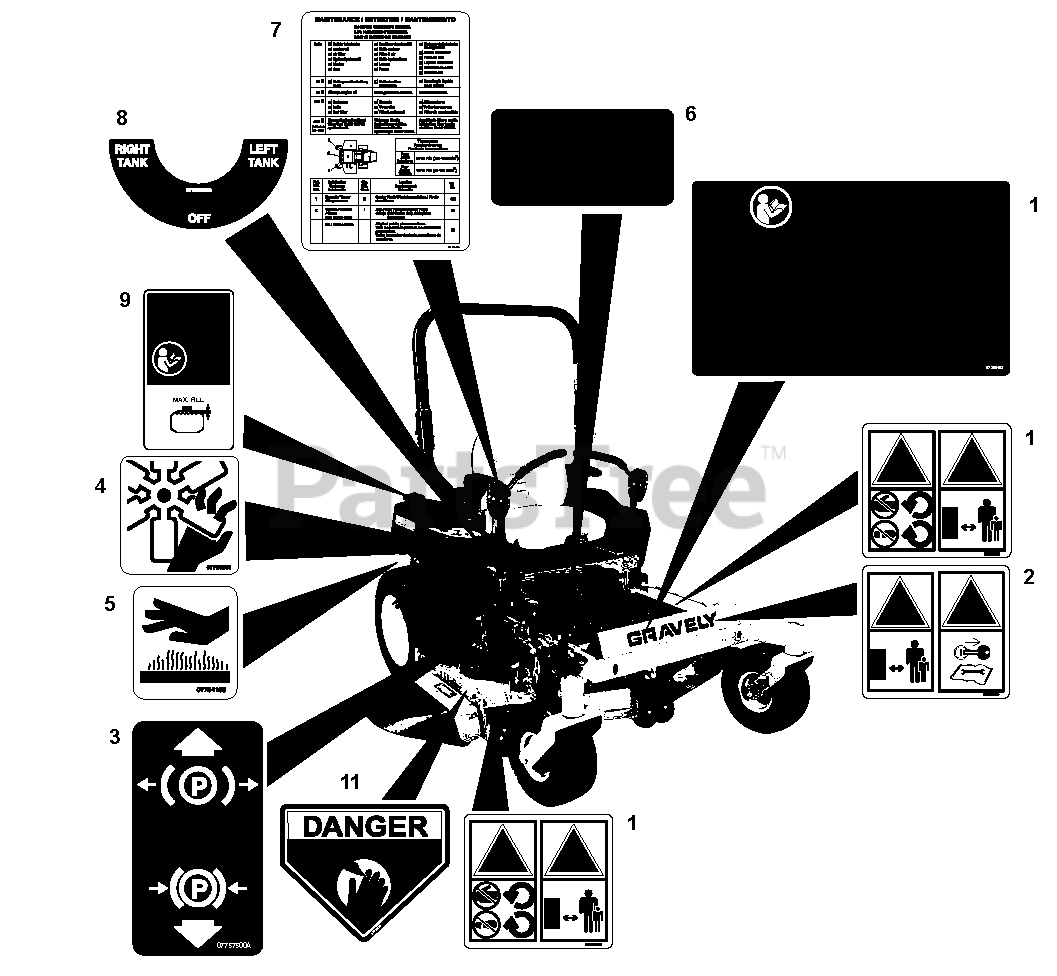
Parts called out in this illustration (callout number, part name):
1	Decal, CE Deck
2	Decal, CE Caution
3	Decal, Parking Brake Lever
4	Decal, Danger Fan
5	Decal, Hot Surface
6	Decal, Safety Guarding
7	Decal, Maintenance Instructions
8	Decal, Fuel Control Valve
9	Decal, Fuel Warning
10	Decal, Main Safety Commercial
11	Decal, Danger
